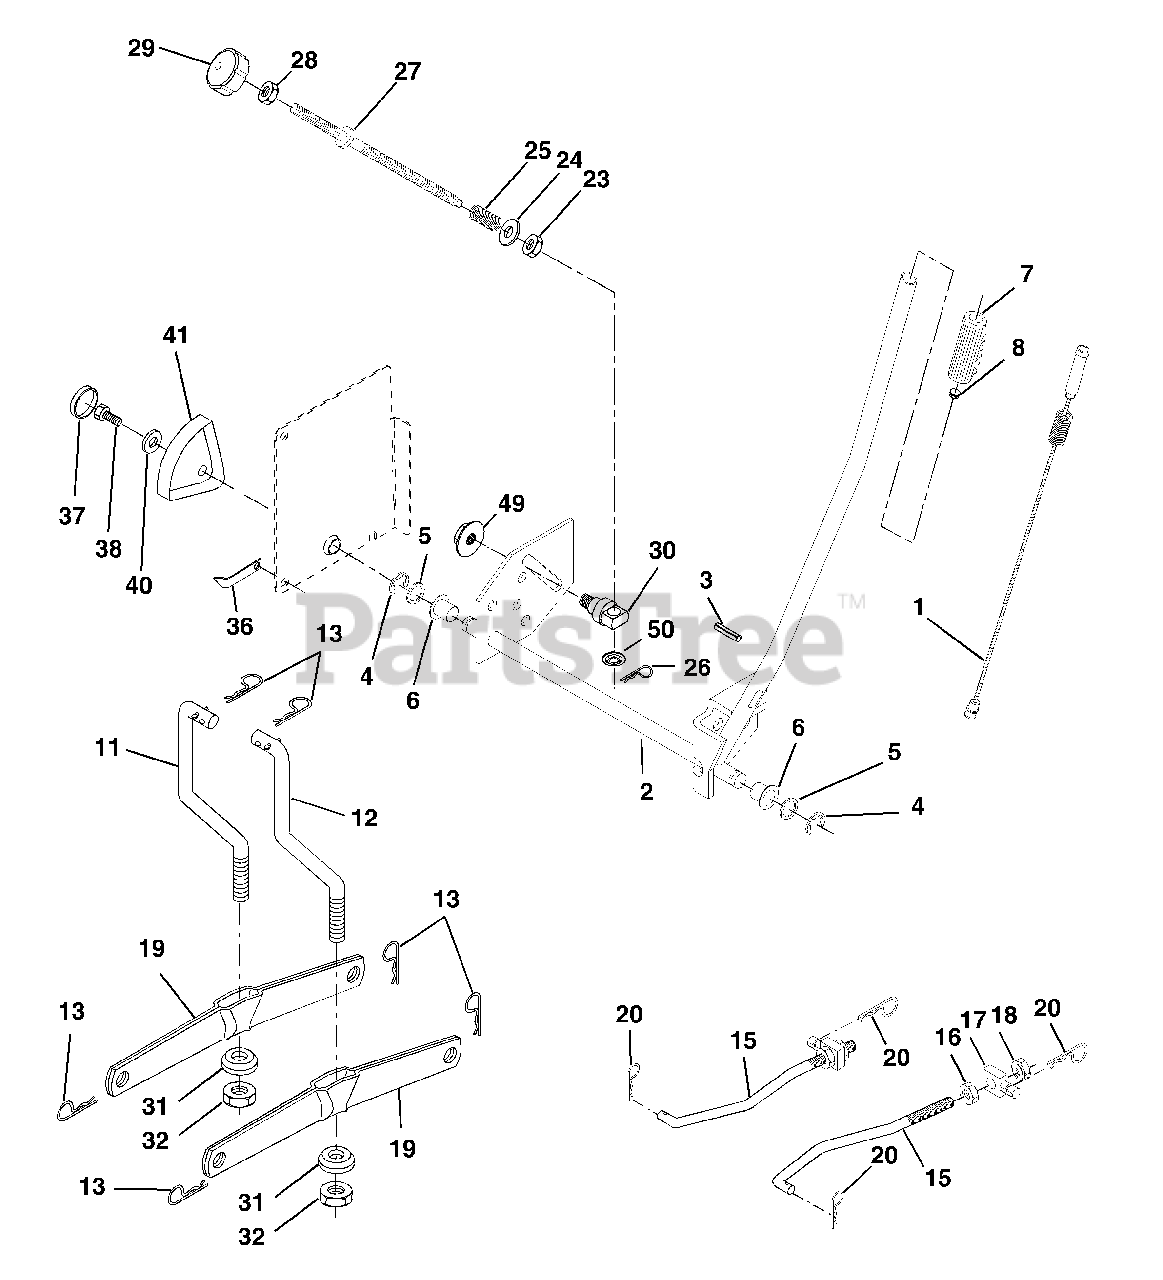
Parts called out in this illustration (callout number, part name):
1	Wire Asm Inner/Sprg W/plunger LT
2	Shaft Asm Lift RH w/Inf
3	Pin Groove 1 500 Zinc
4	E Ring #5133-62
5	Washer 21/32 X 1 X 21 Ga
6	Bearing Nylon Blk 629 Id
7	Grip Handle
8	Button Plunger Yellow
11	Link Lift LH Fixed Length
12	Link Lift RH Fixed Length
13	Retainer Spring
15	Link Front
16	Nut Jam Hex 1/2-13 Unc
17	Trunnion Blk Zinc
18	Nut Lock w/Wsh 1/2-13 Unc
19	Arm Suspension Rear
20	Retainer Spring
23	Nut Special
24	Washer 13/32 X 5/8 X 16 Ga
25	Spring 2-1/8"
26	Retainer Clip
27	Rod Adj Lift Zinc 7.49 Wrk Lg
28	Nut Hex Jam 3/8-16 Unc
29	Knob Inf 3/8-16 Unc Blk W/sym
30	Trunnion Infin Height
31	Bearing Pvt Lift
32	Nut Crownlock 3/8 - 24
36	Pointer Height Indicator
37	Plug Hole Blk 1.485/1.515 Dia.
38	Screw Thdrol 5/16-18 x 1
40	Washer 11/32 x 1-1/2 10 Ga.
41	Indicator Height STLT
49	Nut Hex Flange Lock
50	Nut PUsh Phos & Oil
